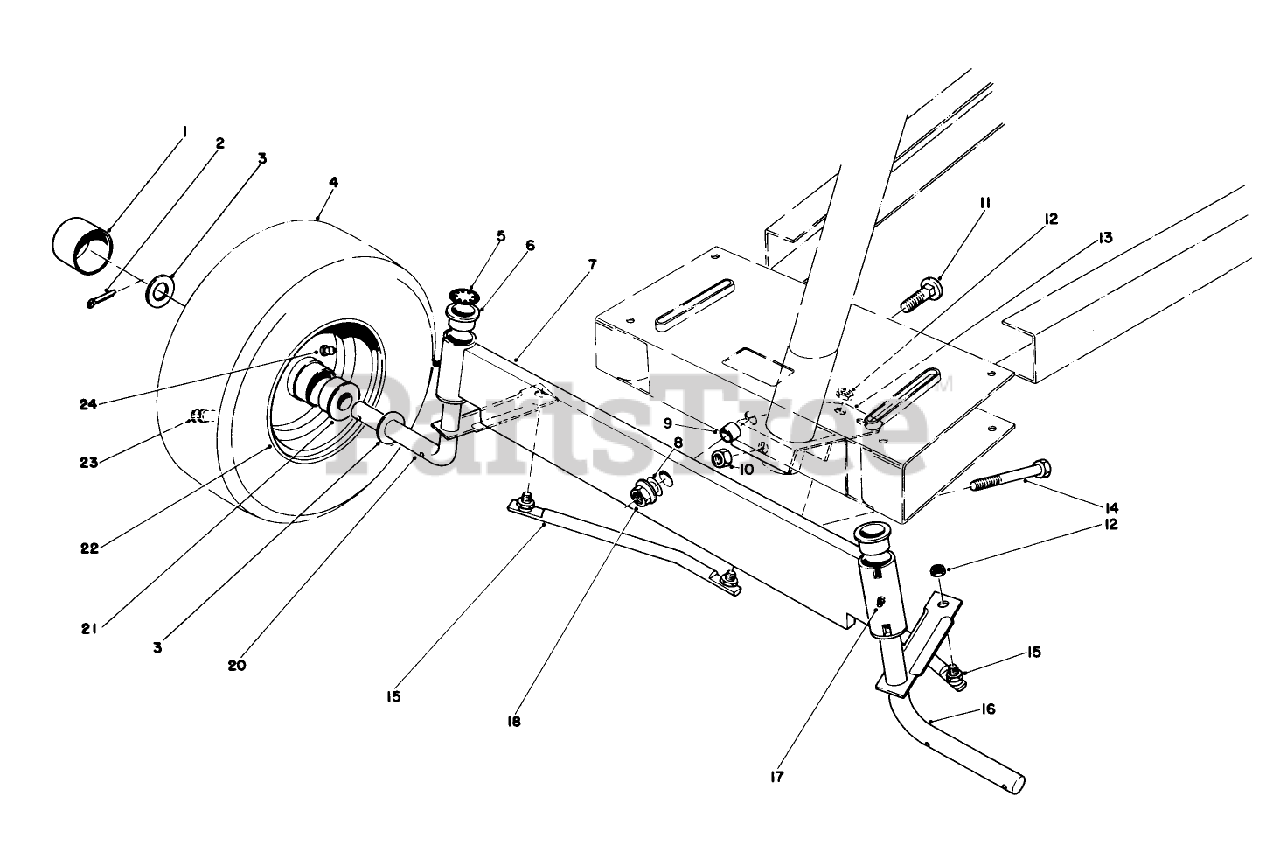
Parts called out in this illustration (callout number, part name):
1	BLACK CAPLUG
2	PIN-COTTER
3	WASHER
4	TIRE,PNEU.11X4.00X5
5	RING-RETAINING
8	WASHER-THRUST
10	NUT-LOCK, NI
11	SCREW-CARR
12	NUT-LOCK, NI
14	SCREW-HH
15	TIE ROD ASM
17	GREASE FITTING
18	NUT-HF
21	BUSHING
24	FITTING-GREASE
